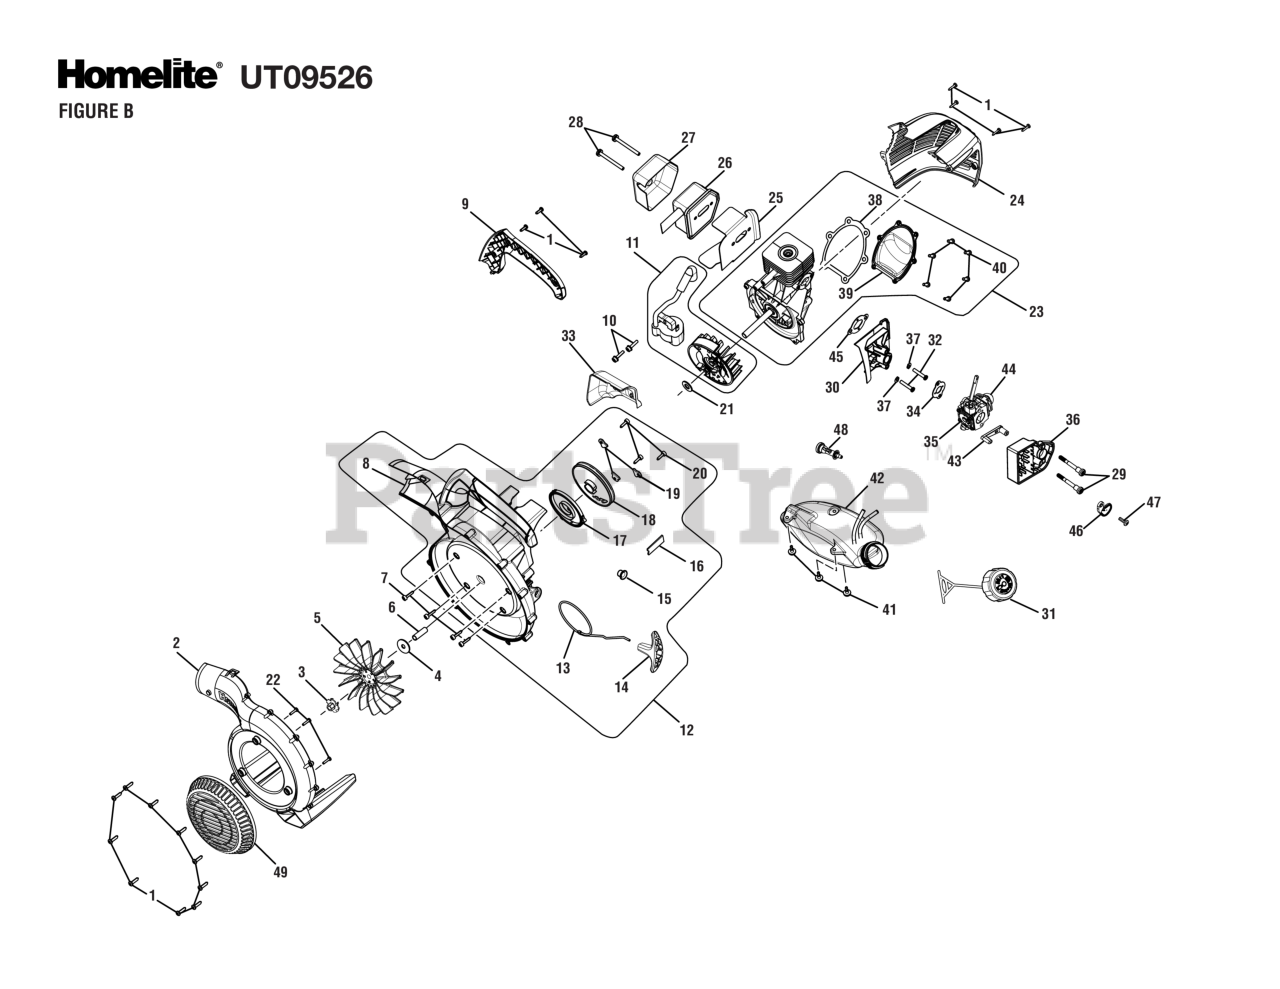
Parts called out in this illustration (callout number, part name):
1	Screw (M4 x 18 mm, T20 Torx Pan Hd. S.T.)
2	Outer Volute w/Label
3	Lock Nut (3/8 in.)
4	Washer (ID9.8 x OD34.27 x 2.28t)
7	Screw w/Washer (M4 x 16 mm, T25 Torx Truss Hd.)
8	Inner Volute w/Eyelet and Label
9	Handle Cover
10	Screw w/Washer (M4 x 19 mm, T20 Torx Pan Hd. S.T.)
11	Ignition Module and Flywheel Kit
12	Lower Housing w/Starter and Label Assembly
13	Starter Rope (42 in.)
14	Pulley Handle
17	Spring & Container Assembly
18	Starter Pulley
19	Pulley Retainer
20	Screw (M4 x 14 mm, T20 Torx Truss Hd T.F.)
21	Washer (ID9.70 x OD20 x 1.59t)
22	Screws (10-14 x 3/4 in., T25 Torx Pan Hd. T.F.)
23	Short Block Assembly
24	Engine Cover w/Label
25	Muffler Gasket
26	Muffler Assembly
27	Muffler Heat Shield
28	Screw w/Washers (10-24 x 2-1/8 in., T25 Torx Truss Hd.)
29	Shoulder Bolt (M5 x 46.5 mm)
31	Fuel Cap Assembly (Inc. Tether)
32	Screw (M5 x 25 mm, T20 Torx Hd.)
33	Baffle Plate
34	Heat Dam Gasket
35	Carburetor
36	Air Box Base
38	Crankcase Cover Gasket
39	Crankcase Cover
40	Screw (M4 x 12 mm, T20 Torx Hd.)
41	Shoulder Screw w/Washer (M4 x 14 mm, T25 Torx Truss Hd.)
42	Fuel Tank Assembly (Inc. Fuel Lines)
43	Choke Lever
44	Primer Bulb (Ruixing)
45	Inner Heat Dam Gasket
46	Choke Cover
47	Screw (M4 x 12 mm, Slotted Recessed Pan Hd.)
48	Fuel Filter
49	Blower Door
